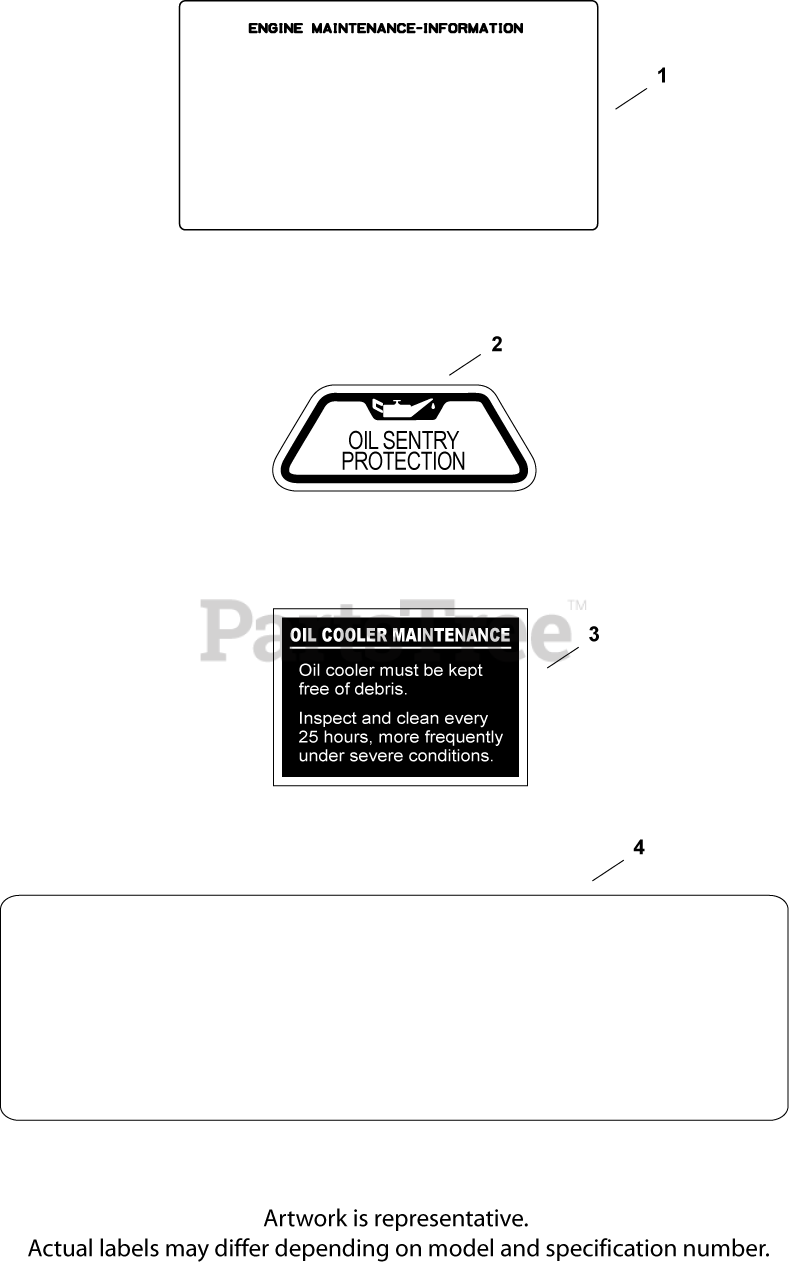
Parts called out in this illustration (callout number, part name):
1	DECAL, ENGINE MAINT. - (#DSC)
2	DECAL, OIL SENTRY - (#DSC)
3	DECAL, OIL COOLER - (#DSC)
4	DECAL, 22 HP
